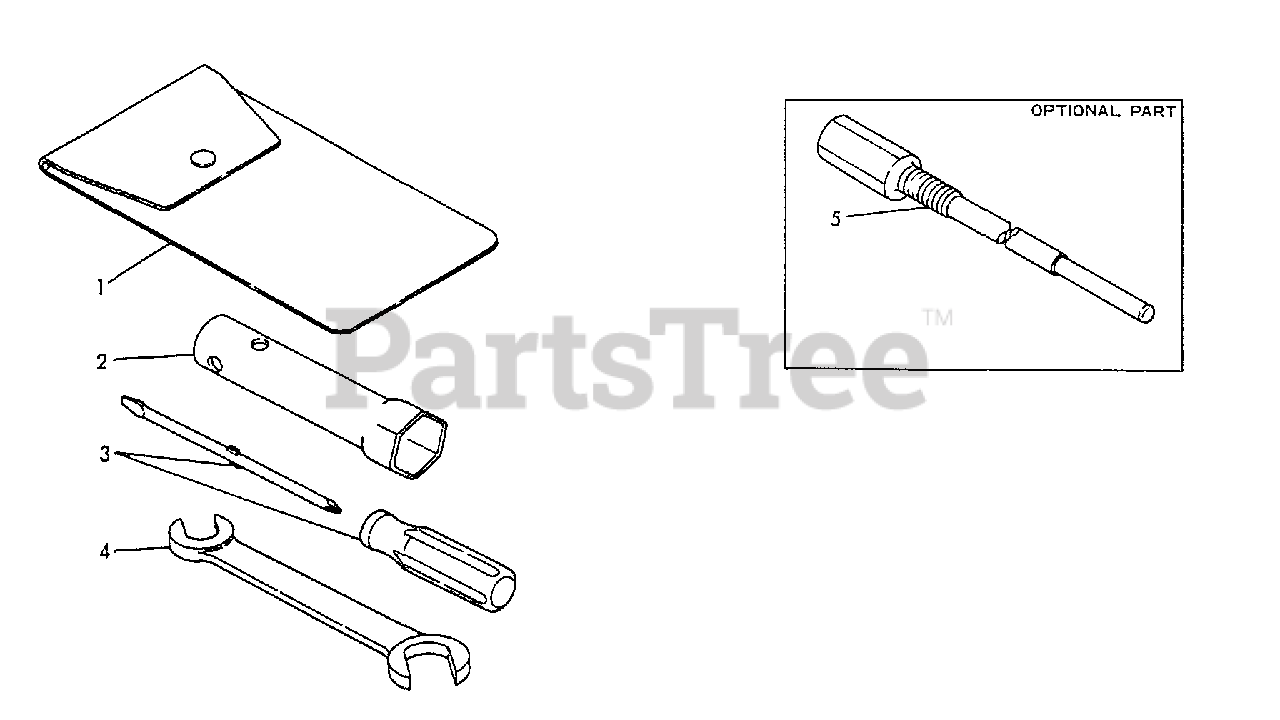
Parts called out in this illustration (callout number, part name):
1	BAG, TOOL
2	SOCKET WRENCH - 21mm
3	SCREWDRIVER
4	SPANNER - 10X12mm
5	TOOL, ROTOR REMOVAL
